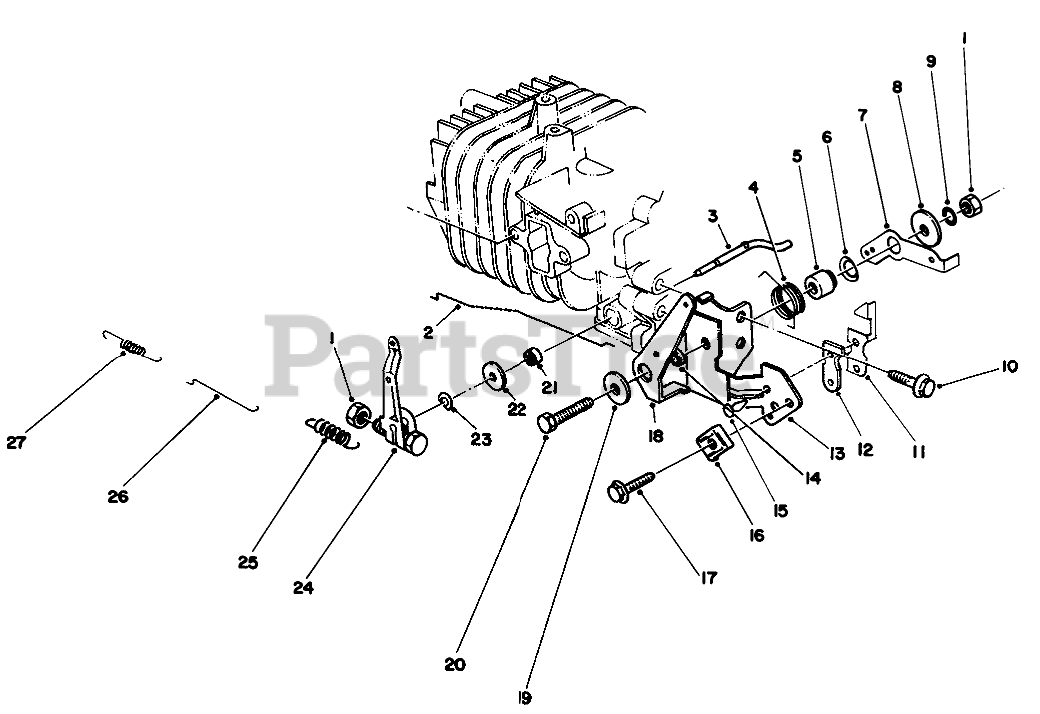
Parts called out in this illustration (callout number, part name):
2	CHOKE ROD
3	Shaft-Govemor
4	SPRING-CHOKE LEVER
5	Gov Lever Spacer
6	Washer-Gov. Spring Lever
7	LEVER-SPRING, GOVERNOR
8	WASHER
9	LOCKWASHER
11	TERMINAL-KILL SWITCH
12	INSULATOR-KILL SWITCH
13	BRACKET-THROTTLE, CONTROL
14	SPACER-CHOKE LEVER
15	KILL SWITCH RIVET
16	CLAMP
18	LEVER-CONTROL, CHOKE
19	WASHER
21	SEAL-OIL
22	WASHER
23	E-RING
24	GOVERNOR ARM
25	SPRING-GOVERNOR
26	ROD-CARBURETOR
27	SPRING
